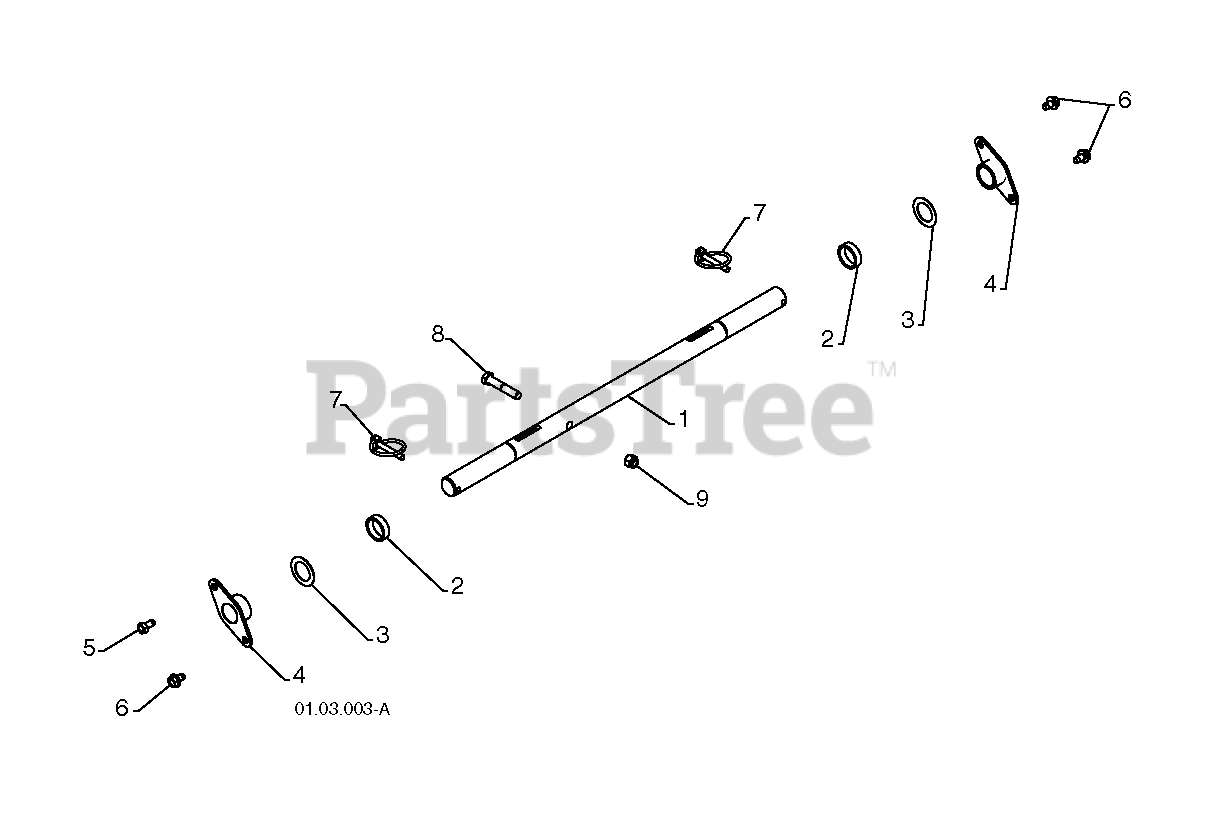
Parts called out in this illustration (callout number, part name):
1	SHAFT.AXLE.POWER.STEERING.HYD
2	SPACER.AXLE.RH
3	WASHER TRUST 1"
4	BEARING, AXLE
6	SCREW LT
7	PIN KLIK, 1/4
8	CAP.SCREW.HEX.HD.3/8-16
9	NUT
